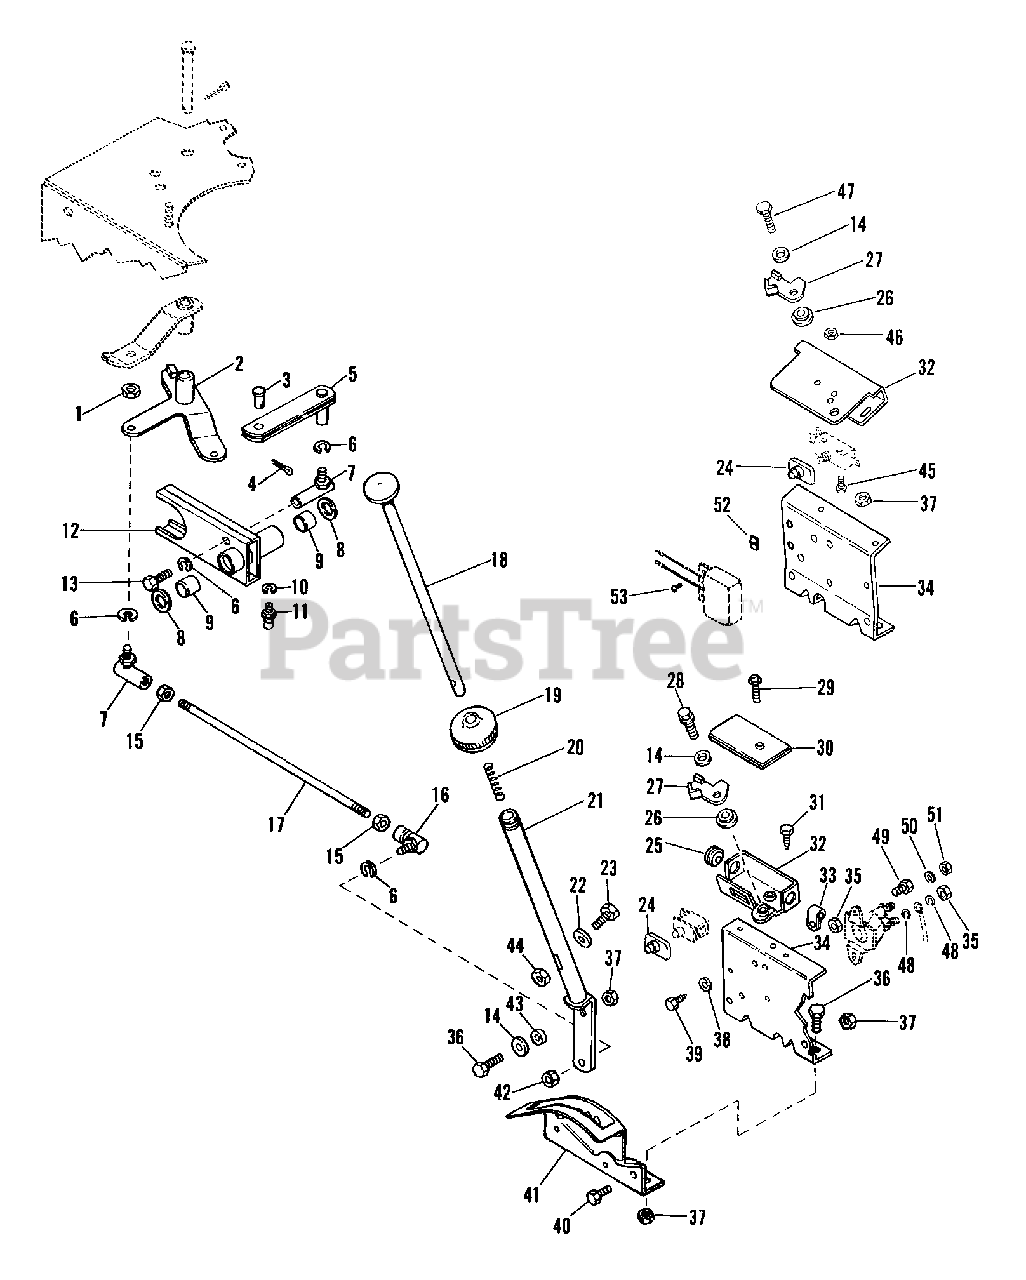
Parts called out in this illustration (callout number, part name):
1	NUT-LK .312-24
2	SHIFT TRANSFER LEVER
3	CLEVIS PIN
4	PIN-COTR .09X.75 PL
5	SHIFT LINK
6	WSHR-LK .312X.097 PL HVY
7	BALL JOINT
8	SEAL .625X.875X.125
9	BSHG-SLV .625X.750X.500 BR
10	WSHR-LK .250X.047 LT PL
11	SPIN DRIVE ZERK FITTING
12	SLIDING FORK ASSEMBLY
13	BLT-HEX .31-24X.50 GR5
14	WSHR-FL-STL .38X.875X.083 PL
15	NUT-HEX .312-24 PL
16	SNAP IN BALL JOINT
17	SHIFT LINK
18	SHIFT RELEASE HANDLE
19	SHIFT BALL
20	SG-COMP ??X.44X?? WLD 10
21	SHIFT LEVER
22	WSHR-FL-STL .281X1.250X.048PL
23	BLT-HEX .25-20X1.25
24	SWITCH BOOT
25	GROMMET, .31 ID
26	BSHG, FLG .325X.499X.26X.88
27	CAM NO SCRAP
28	SCR-TAP .312-18X.75 HWH PL TR
29	SCR-TAP 12-14X1.25 CROVH PL 1A
31	SCR-TAP 10-24X.375 CRPH 1A
32	SWITCH HOUSING
32	SWITCH MOUNT
33	CLAMP
34	SWITCH BRACKET
35	NUT-LK-CTR .250-20 PL
35	NUT-JAM .312-24 PL
36	BLT-HEX .31-18X.75 PL GR2
37	NUT-LK .312-18 GR A PL
38	WSHR-FL-STL .250X.562X.049 PL
39	SCR-TAP 10-16X1.0 SLHP PL AB
40	BLT-HEX .31-18X.50 PL GR2
41	SHIFT CONTROL SEGMENT
42	NUT-LK .312-24
43	SPACER BUSHING .5 X .32 X .21
44	NUT-LK TOP .250-20 PL
45	SCR-MCH 6-32X1.00 SLRH PL
46	NUT-KEPS 6-32 PL
47	BLT-HEX .31-18X.88 PL GR2
48	WSHR-LK-INT .313X.030 PL
49	BLT-HEX .25-20X.50 PL GR2
50	WSHR-LK-EXT #10 ID X .022
51	NUT 10-32 PL
52	NUT-KEPS 10-24 PL
53	SCR-MCH 10-24X.38 SLTOR PAN PL
